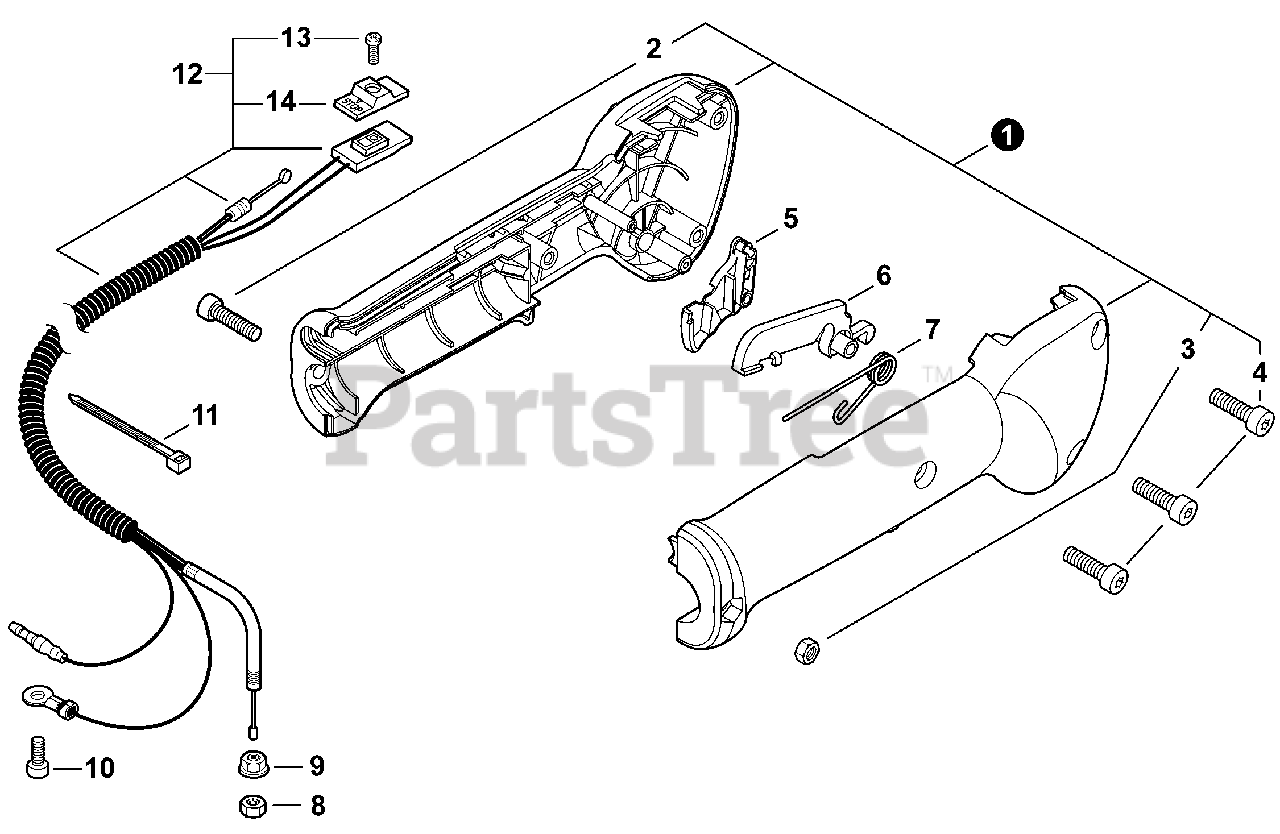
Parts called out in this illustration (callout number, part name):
1	CONTROL HANDLE KIT
2	BOLT, TORX 5×30
3	NUT M5
4	BOLT, TORX 4×16
5	TRIGGER, THROTTLE
6	LOCKOUT, THROTTLE
7	SPRING, TORSION
9	NUT, FLANGE M6
10	BOLT, TORX 4×10
11	STRAP, TIE
12	CABLE ASSY, CONTROL
13	SCREW 3×10
14	KNOB, SWITCH - ORANGE
